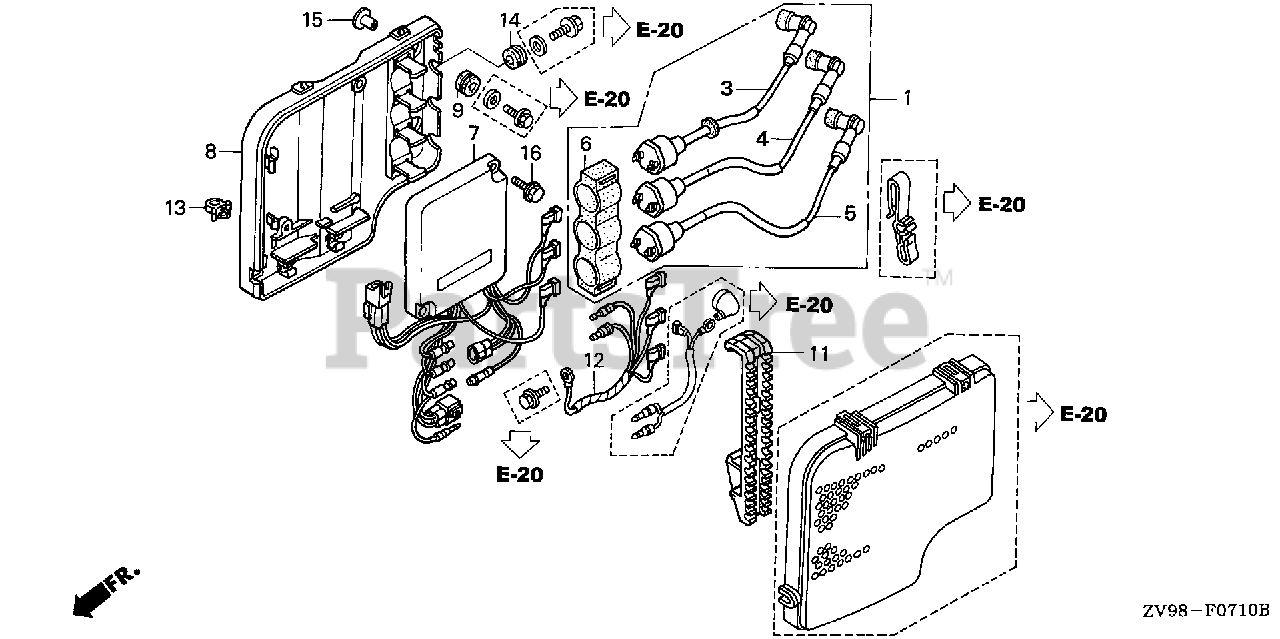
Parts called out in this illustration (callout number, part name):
1	COIL ASSY., IGNITION
3	COIL, IGNITION (1)
4	COIL, IGNITION (2)
5	COIL, IGNITION (3)
6	SUSPENSION, IGNITION COIL
7	MODULE, IGNITION CONTROL (CDI)
8	CASE, IGNITION CONTROL MODULE (CDI)
9	GROMMET, MODULE IGNITION CONTROL CASE (CDI)(B)
11	BRACKET, CONNECTOR (A)
12	WIRE ASSY., GROUND
13	CLIP, TURN SIGNAL WIRE
14	GROMMET, CASE (LOWER)
15	COLLAR, MODULE IGNITION CONTROL CASE (CDI)
16	BOLT, FLANGE (6X20)
